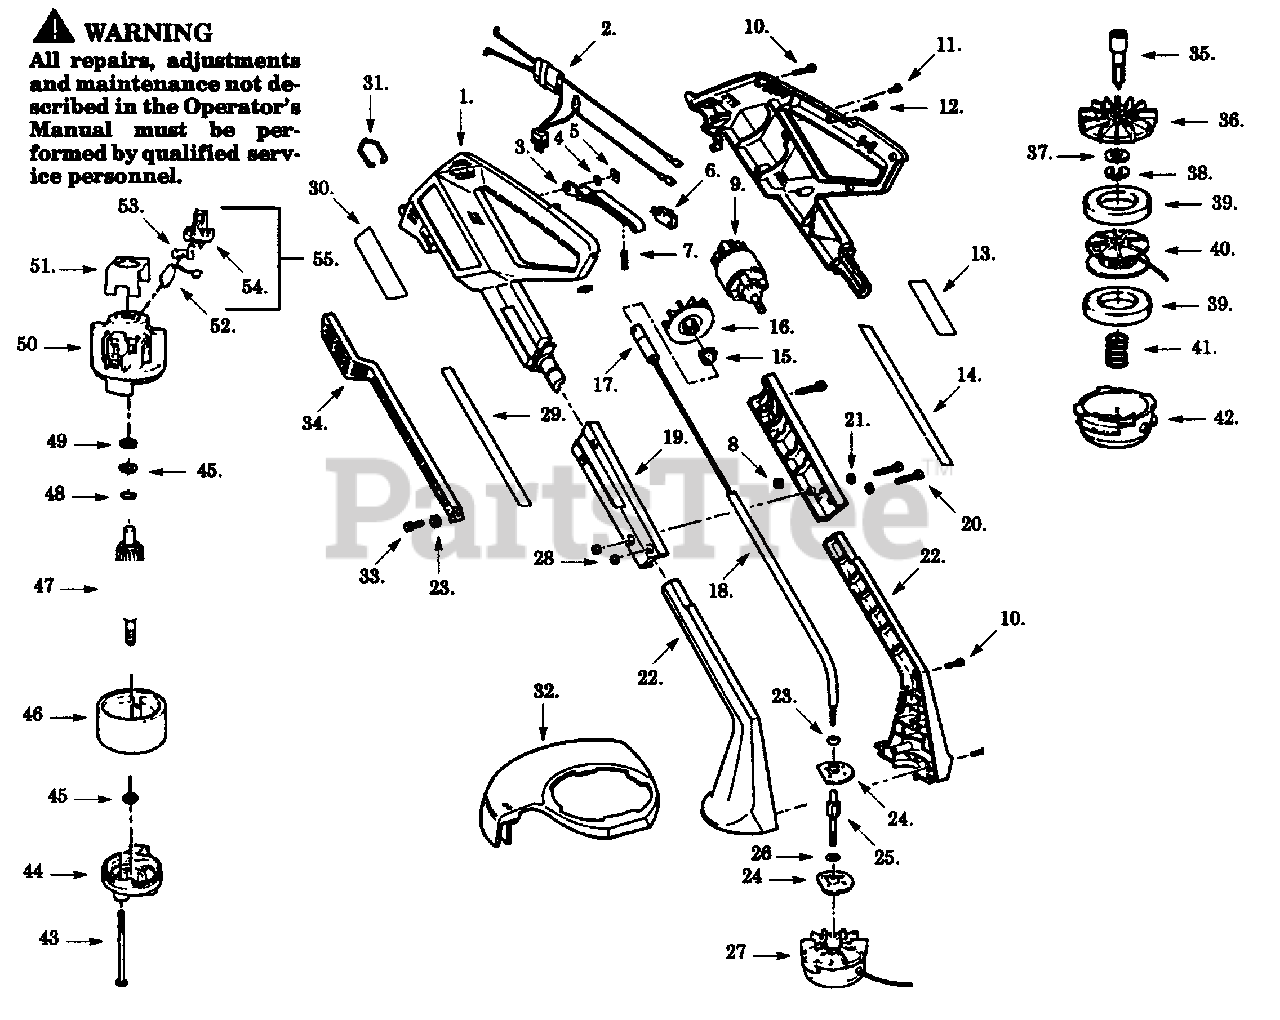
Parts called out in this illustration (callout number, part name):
1	Motor Hsg. Set
5	Push Nut
7	Trigger Spring
8	Square Nut
9	Motor Ass'y.
13	Warning Label (Not a serviceable part)
14	Logo Label (L)
15	Fan Clamp
17	Flex Shaft Ass'y.
18	Sleeve Tubing
19	Housing Clamp
22	Spindle Housing
24	Bearing Holder Disk
25	Shaft Adapter
27	Cutting Head Ass'y.
29	Logo Label (R)
30	Nameplate Label (Not a serviceable part)
32	Guard Ass'y.
34	Assist Handle
35	Drive Adapter
36	Rear Plate
38	Retaining Ring
39	Foam Pad
40	Spool & Line
42	Hub Ass'y.
44	Endbell Ass'y. (Drive)
46	Field Ass'y.
47	Armature Ass'y.
48	Retaining Ring
50	Endbell Ass'y. (Brush)
51	Insulator
53	Brush Spring
54	Brush Holder
55	Brush Kit (Incl. 52,53,54)
